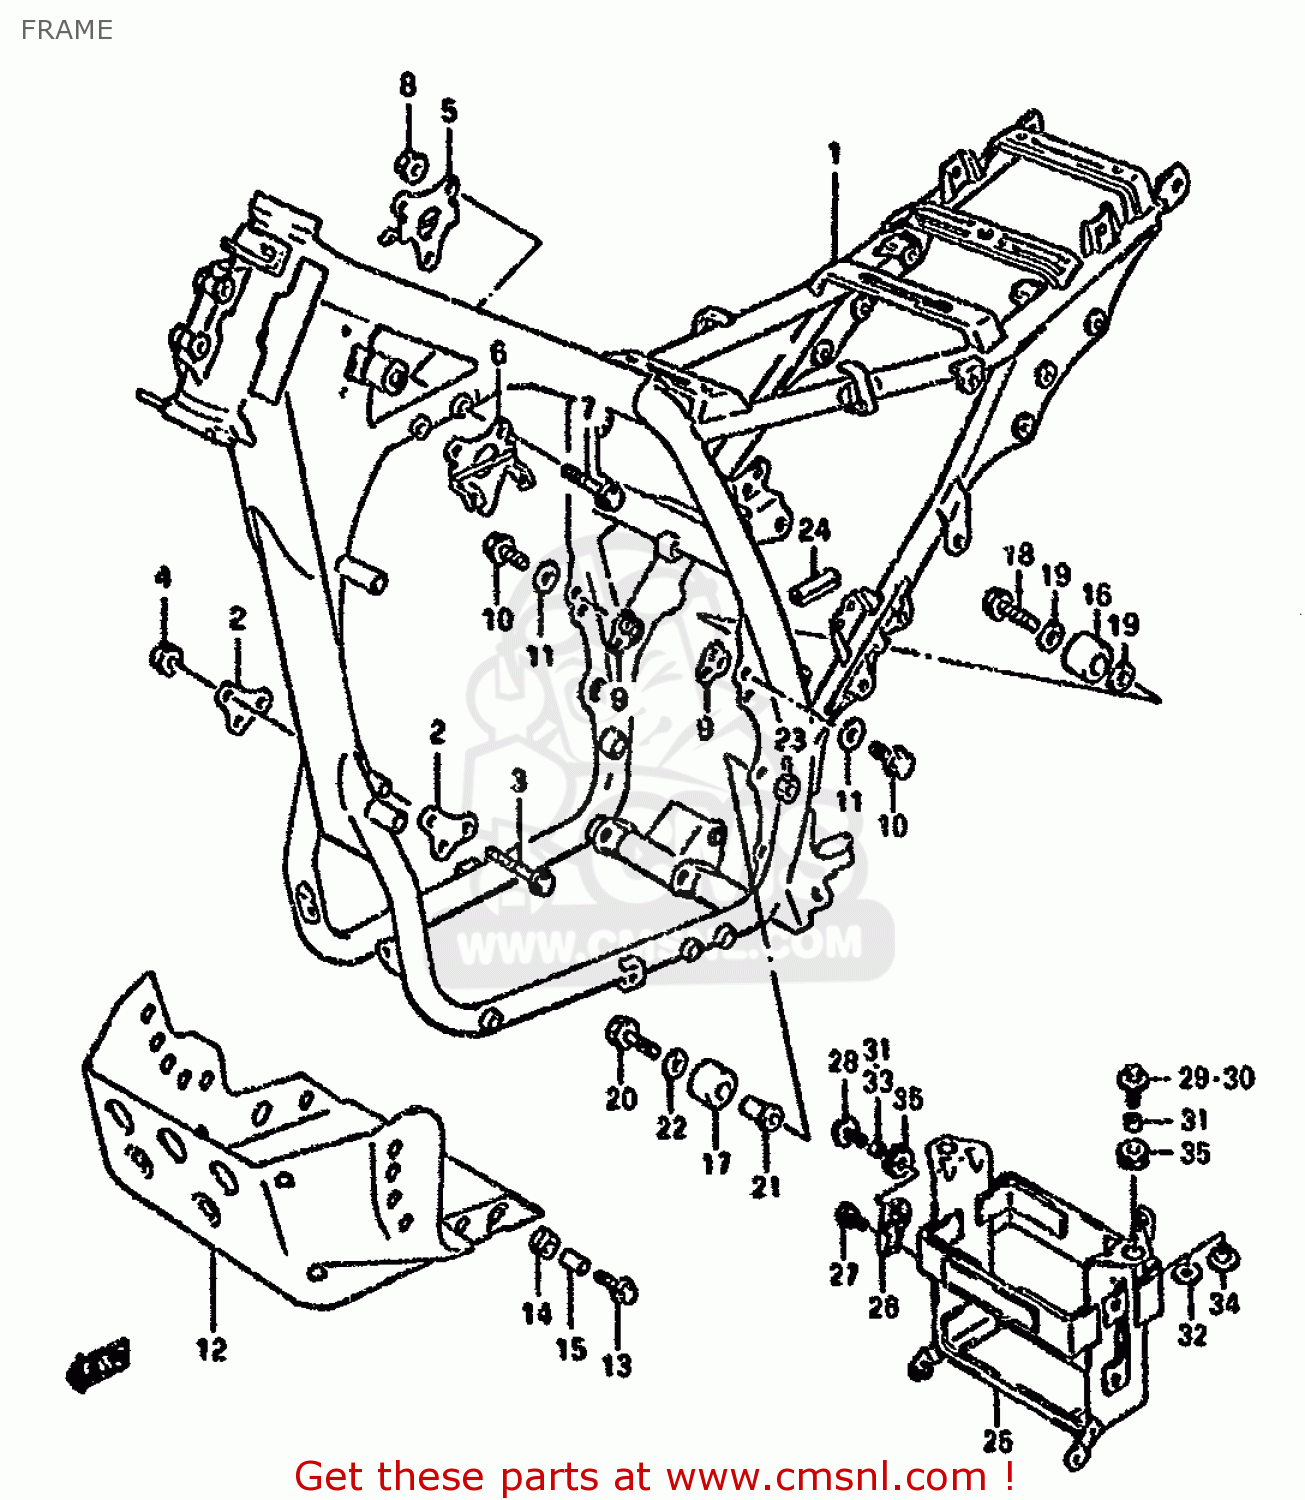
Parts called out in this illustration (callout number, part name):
1	FRAME (WHITE)
2	PLATE,ENG MTG FR
3	BOLT(8X70)
4	NUT
5	PLATE,ENG MTG UPR,R
6	PLATE,ENG MTG UPR,L
7	BOLT
8	NUT
9	PLATE, REAR (BLACK)
10	BOLT
11	LOCK WASHER
12	PROTECTOR,ENGINE
13	BOLT(6X20)
14	CUSHION
15	SPACER (6.1X9X9)
16	ROLLER,CHAIN
17	ROLLER,CHAIN CONTROL
18	BOLT(8X41)
19	WASHER
20	BOLT(10X52)
21	SPACER,CHAIN ROLLER, LWR
22	WASHER
23	NUT 10MM
24	MOLDING
25	HOLDER,BATTERY
26	PLATE, SIDE
27	BOLT
28	BOLT 6X20
29	BOLT(6X25)
30	BOLT(6X25)
31	SPACER(6.1X9X7.5)
32	WASHER (6.5X20X1.2)
33	SPACER(6.1X9X7.5)
34	SPACER COMP,BATTERY
35	CUSHION
